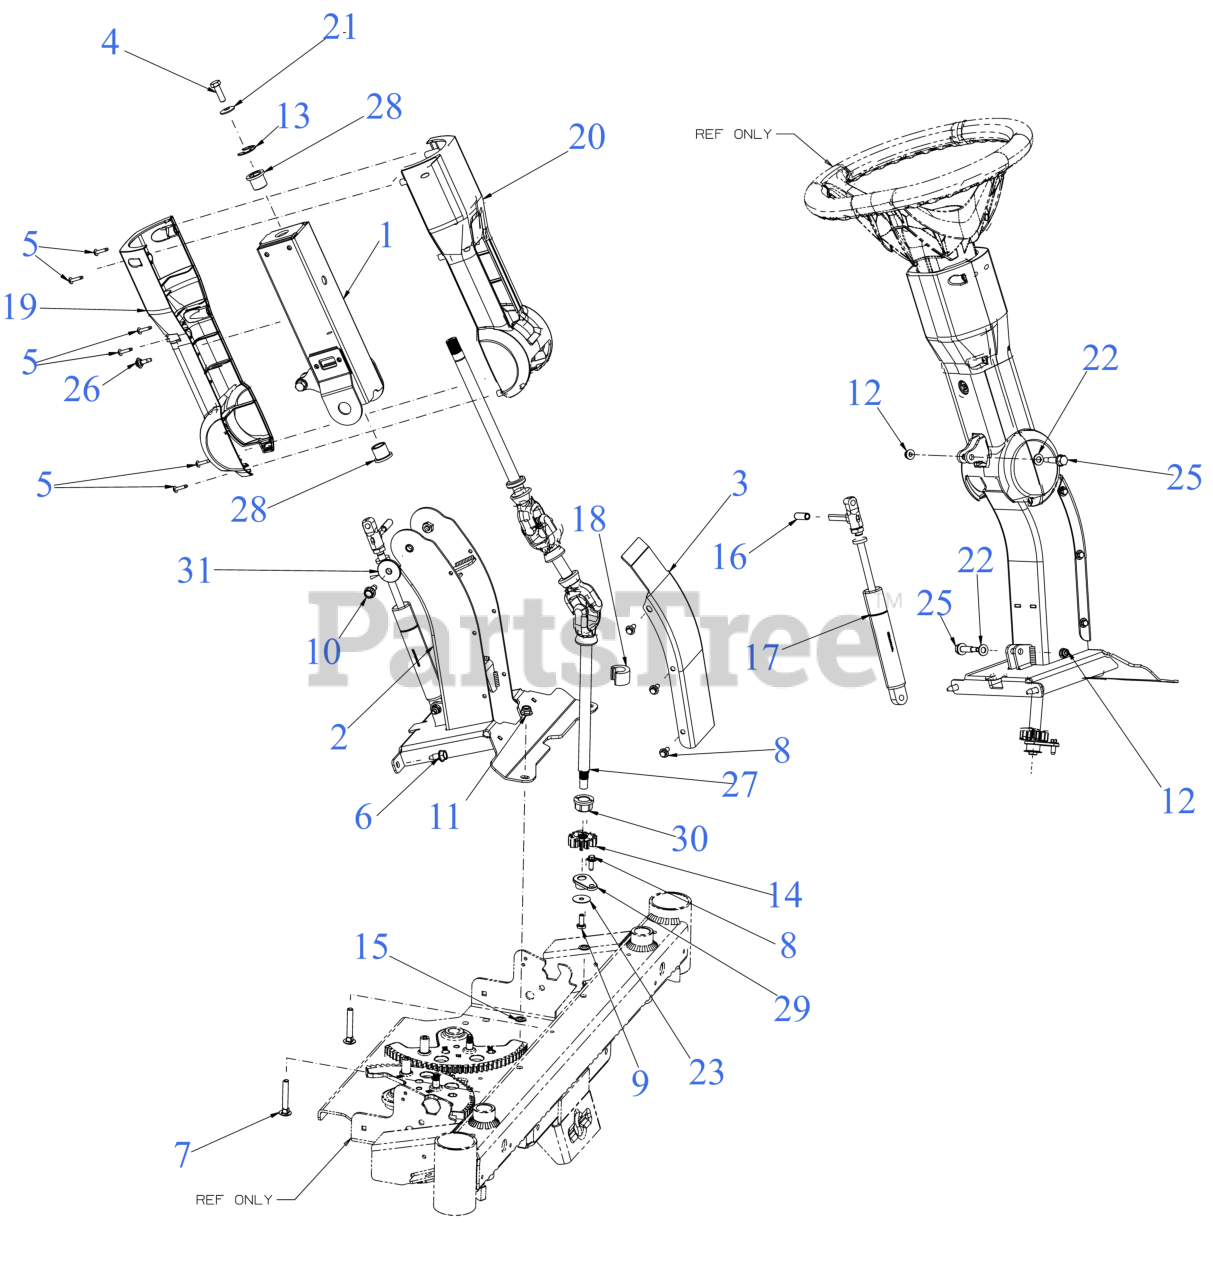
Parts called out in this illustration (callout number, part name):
1	STEERING COLUMN (UPPER)
2	STEERING COLUMN (LOWER)
3	STEERING COLUMN COVER
4	HEX HEAD CAP SCREW 5/16-24 x 1.00 GR5
5	SCREW 8-16 x 3/4
6	SCREW 5/16-18 x .750
7	CARRIAGE BOLT 5/16-18 x 2.00 GR5
8	SCREW M6-1 x .625
9	SCREW 1/4-20 x .620 GR5
10	SCREW 5/16-18 x .750
11	FLANGE LOCK NUT 5/16-18
12	FLANGE LOCK NUT
14	STEERING GEAR 14T
17	TILT STEERING CYLINDER
18	SNAP SPACER
19	STEERING COLUMN COVER (BACK)
20	STEERING COLUMN COVER (FRONT)
21	BELL WASHER .337 X.867 x .057
22	FLAT WASHER
23	FLAT WASHER
25	SHOULDER SCREW
26	SHOULDER SCREW M6-1 .368 X.115
27	STEERING SHAFT
28	FLANGE BEARING .631 ID
29	FLANGE BEARING
30	HEX FLANGE BEARING
31	SHOULDER SPACER
